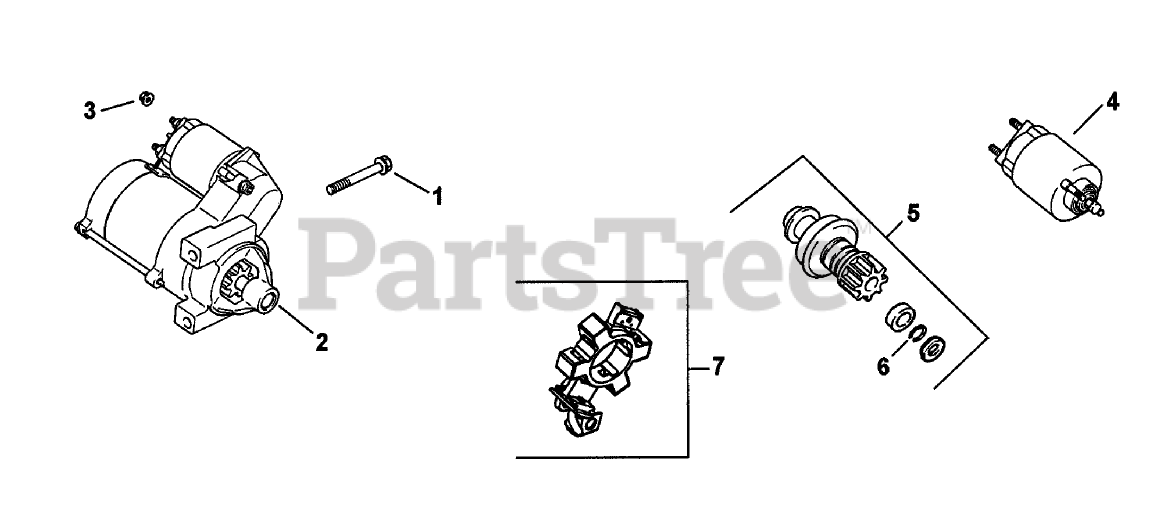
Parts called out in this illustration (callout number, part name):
1	SCREW-FLG (M8X1.25X80)
2	Solenoid Shift Starter ASM (Includes 4-7)
3	NUT-FLANGE (M8X1.25)
4	Solenoid Kit
5	Kit-Drive, Pinion (Includes 6)
6	RING-RETAINING
7	BRUSH HOLDER KIT
